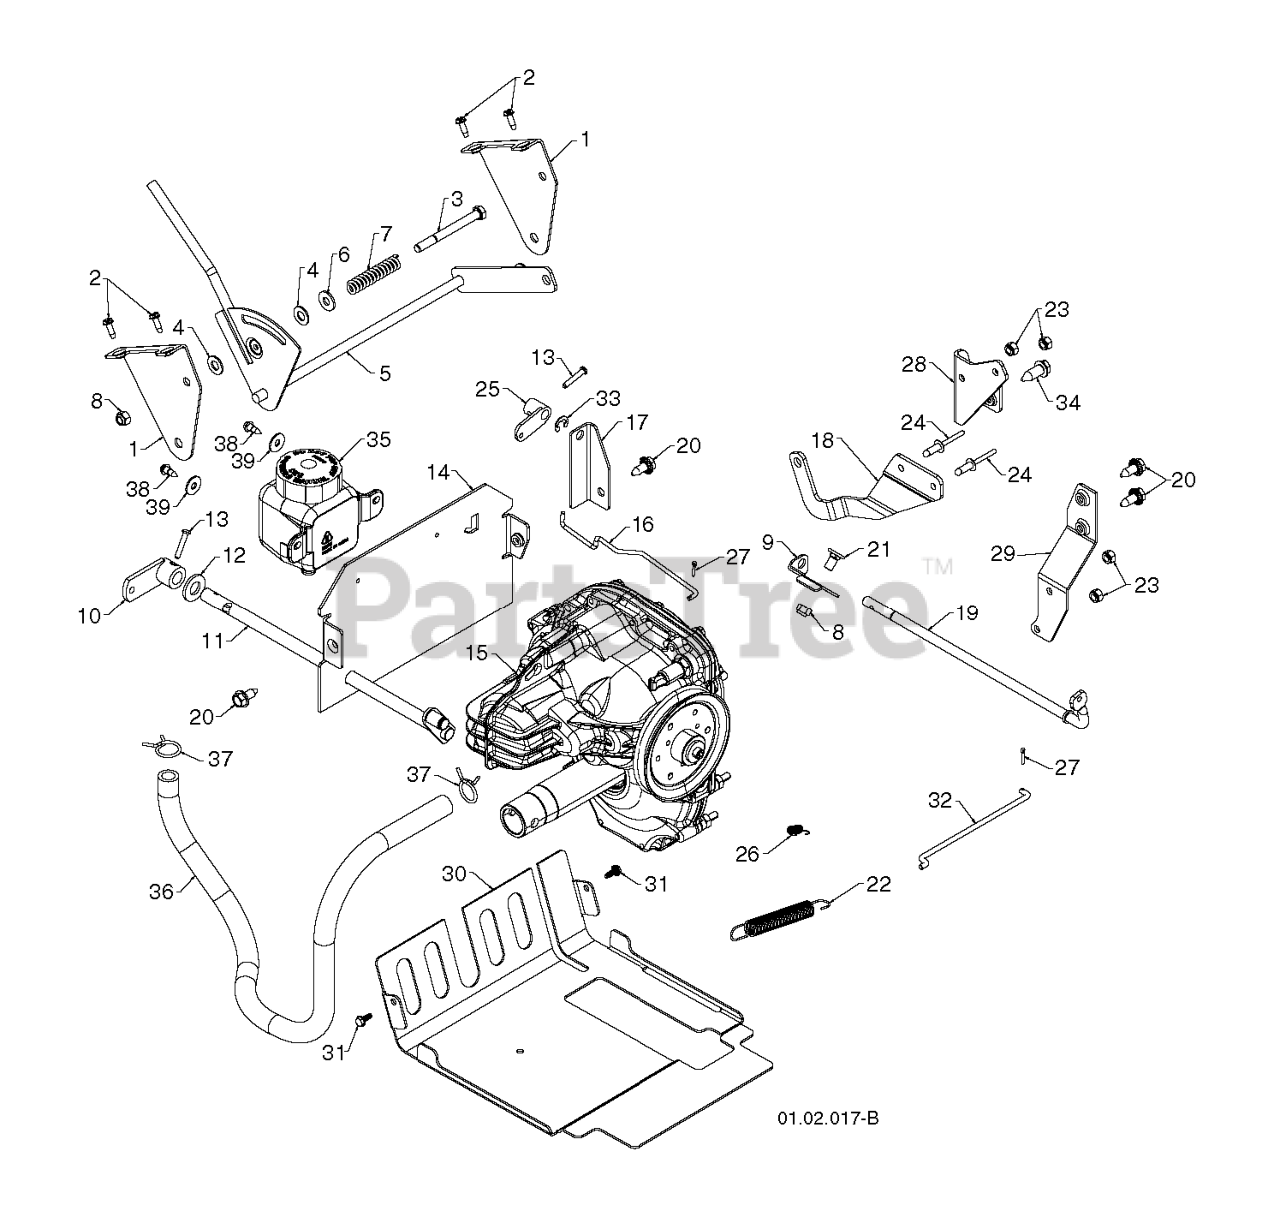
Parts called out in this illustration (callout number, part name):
1	BRACKET.SHIFT.HYDRO
2	SCREW #10-24 X 5/8
3	SCREW 5/16-18 X 3.25
4	WASHER, NYLON FRICTION
5	LEVER ASSEMBLY, SPEED CONTROL
6	WASHER.20X8.5
7	SRPING.FRICTION.HYDRO
8	NUT.71038.31-18.HEX.NYLOCK
9	BRACKET.HYD.CLUTCH.
10	ARM.CONTRL.PIN.TRACK
11	CONTROL.SHAFT.ASM
12	WASHER.FLAT.1/2
13	CLEVIS PIN
14	PLATE.REAR.HYDRO.ORANGE
15	TRANSMISSION 321-0410
16	ROD, BYPASS VALVE
17	BRACKET.HYD.CLUTCH.REAR
18	ARM.CONTROL.HYDRO.SNOW
19	SHAFT.HYD.CLUTCH
20	BOLT.HEX.HD.WASHER.5/16-18X.75
21	BOLT.CARRIAGE.5/16-18X
22	SPRING, BRAKE
23	LOCKNUT.NYLOC.1/4-20
24	RIVET.POP.1/4X.475
25	ARM.HYD.CLUTCH
26	SPRING, TRACTION IDLER
27	RETAINER CLIP
28	BRACKET, ANTI-ROTATE
29	STRAP.TORQUE.HYDRO
30	BOTTOM PAN
31	SCREW1032X.500
32	RP ROD.HYD.CLUTCH
33	E-RING.RETAINER.REINFORCED.375
34	SCREW 5/16-18X1
35	TANK.EXPANSION.350ML 71328
36	HOSE EXPANSION TANK
37	SPRING HOSE CLAMP.750
38	SCREW, HEX HEAD, TAPPING
39	WASHER
